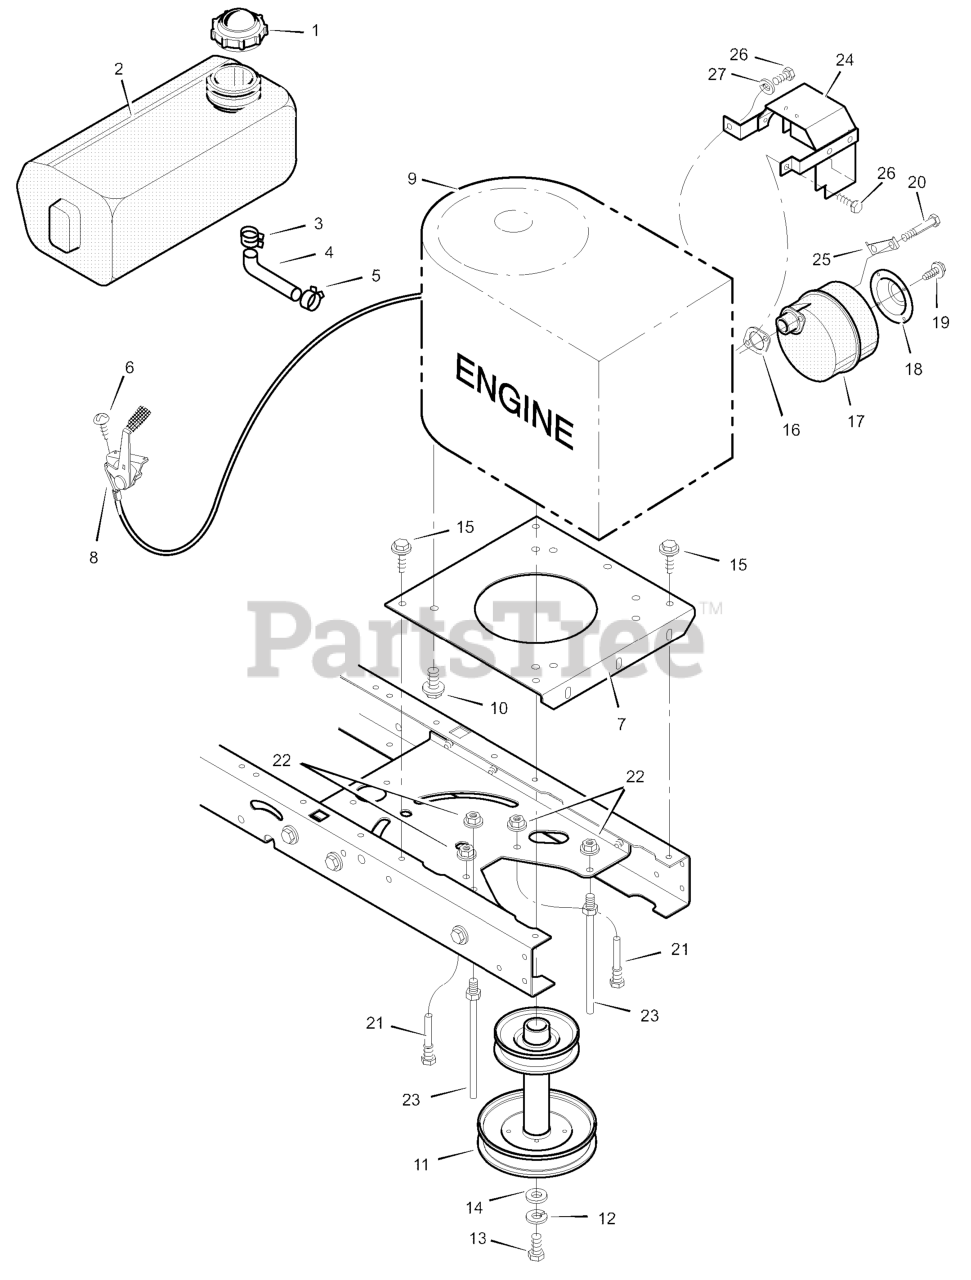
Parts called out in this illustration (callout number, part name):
1	Fuel Cap
2	Fuel Tank
3	Hose Clamp
4	Fuel Line (Must cut to length)
5	Hose Clamp
7	Plate, Engine
8	Throttle Control
9	Engine *
10	Bolt, Engine Mount
11	STACK PULLEY ASSEMBLY
12	Lockwasher
13	Bolt, Hex
16	GASKET, Exhaust
17	Muffler
18	Deflector, Muffler
20	Bolt, Hex
21	Guide, Belt
22	Nut, Flange
23	Guide, Belt
24	Shield, Heat
25	Lock, Screw
